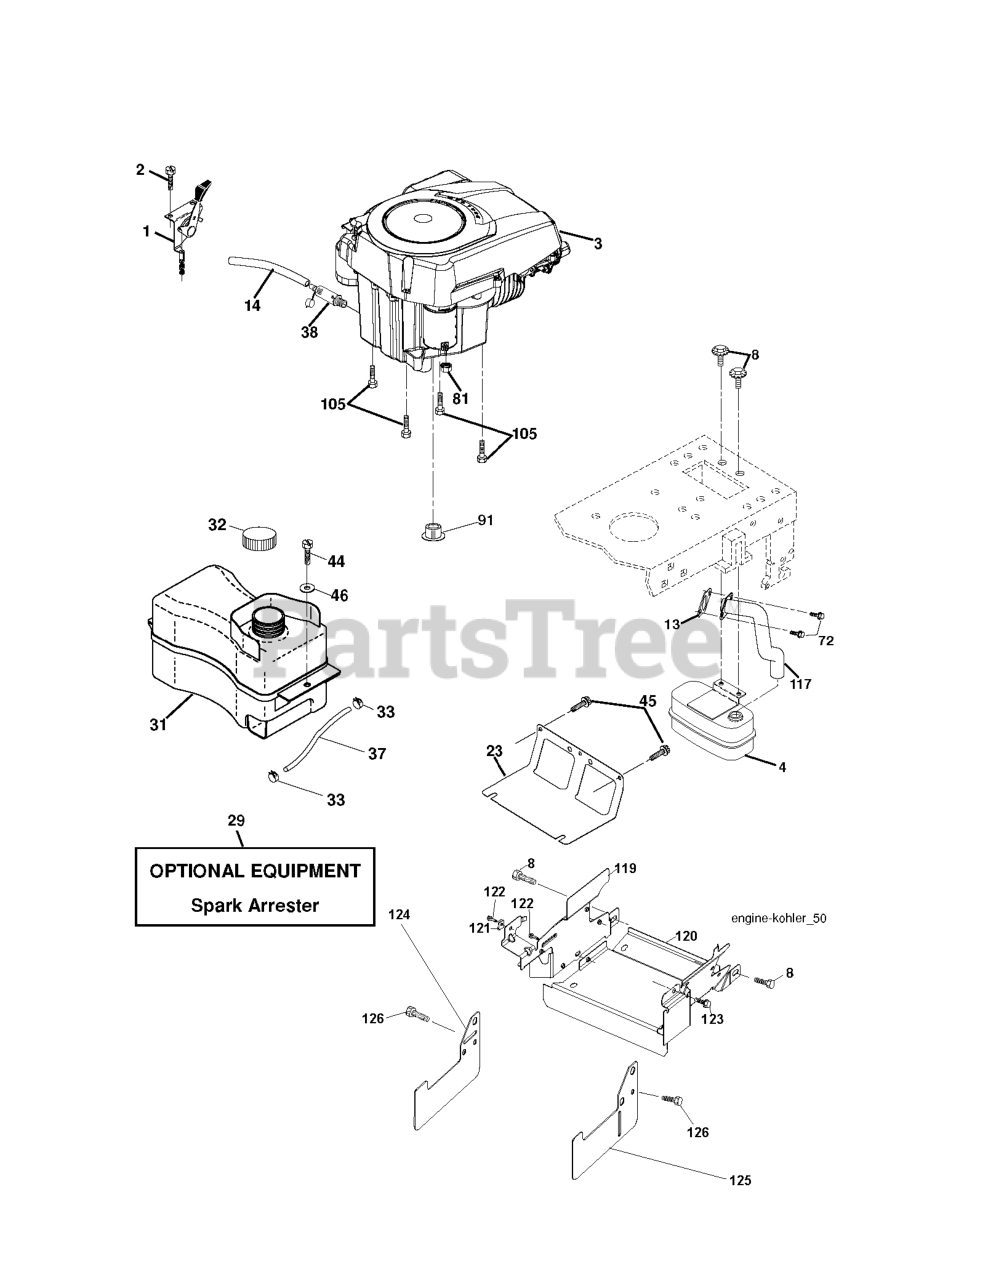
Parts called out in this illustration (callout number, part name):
1	CONTROL.TH/CK.C.
2	SCREW
4	MUFFLER.SINGLE.CYL.KOHL/B&S
8	BOLT.5/16-18UNCX3/4 W/SEMS.BLK
13	GASKET.EXHAUST.KOHLER
14	TUBE, DRAIN OIL ASM.
23	SHIELD.BROWNING.DBR.GUARD
29	KIT.SPARK ARRESTOR 794945 B&S
31	RP TANK FUEL FRT 1.5 GAL
32	FUEL CAP
33	HOSE CLAMP
37	LINE.FUEL.20
38	PLUG DRAIN OIL EASY
44	SCREW HEXWSHR 1/4-20X3/4
45	SCREW, 3/8-16X3/4
72	SCREW.SOCKET HD.5/16-1
81	NUT
91	BUSHING.1.375OD
105	SCREW 3/8-16X1
117	RP.TUBE.EXHAUST.KOHL.COURAGE
119	LENKRAD
120	GUARD 532199767
122	SCREW.1/4-20X5/8
123	SCREW, 5/16-18 X 1/2
126	SCREW
